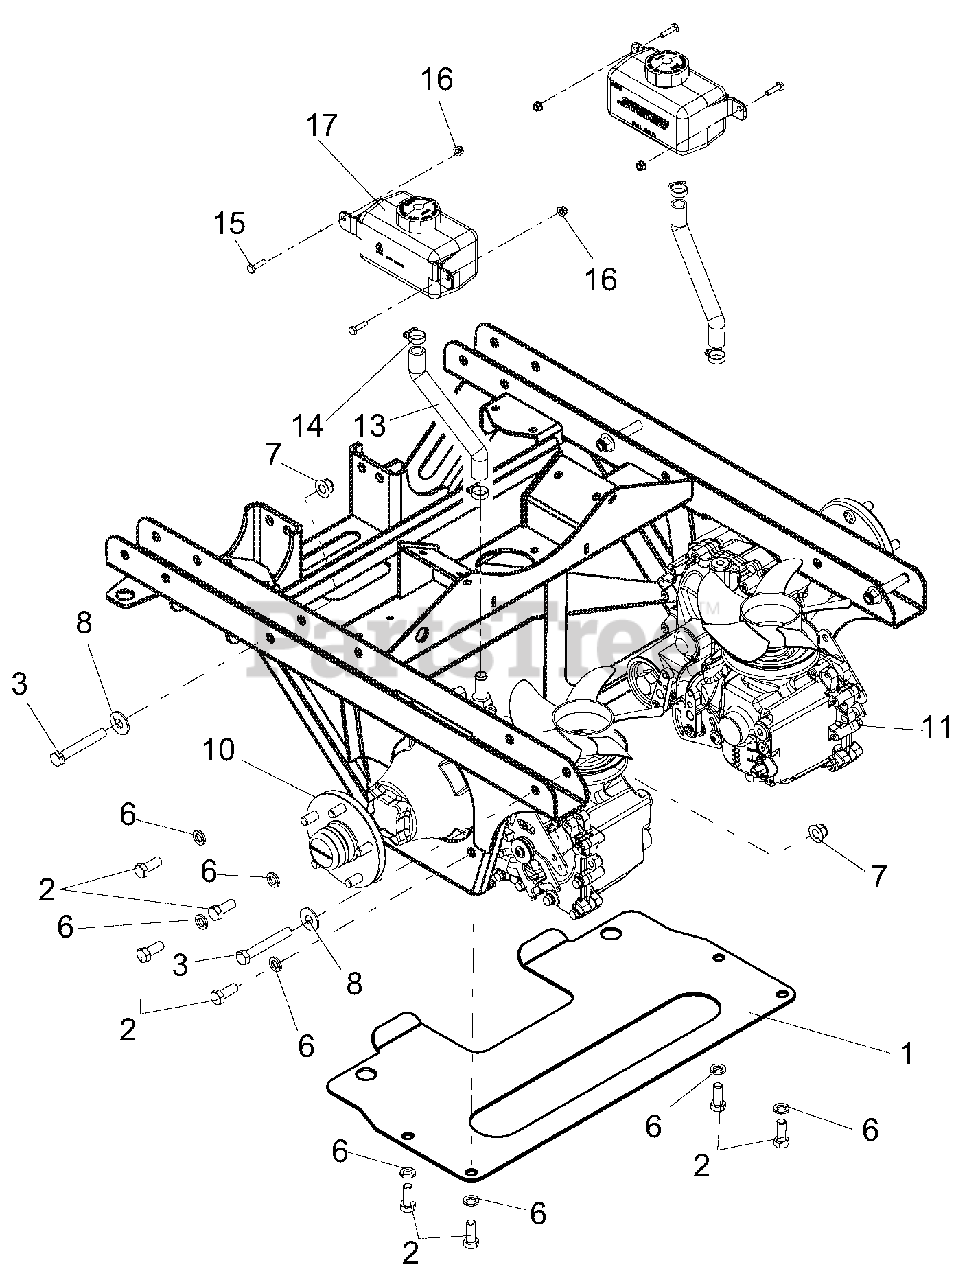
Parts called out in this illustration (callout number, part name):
1	PLATE, TRANSMISSION CONNECTING
2	BLT-HEX .50-13X1.25 GR5 YWZC
3	BLT-HEX .50-13X3.50 GR5 YWZC
6	WSHR-LK .50X.125 REG YWZC
7	NUT-LK-NYL-FLG .50-13 YWZC
8	WSHR-FL-STL.563X1.38X.109YWZC
10	TRANS, R.H. HG ZT-5400
11	TRANS, LH HG ZT-5400
13	HOSE, HYDRO OVERFLOW
14	CLAMP, .88 DIA HOSE
15	BLT-HEX .25-20X1.00 GR5 YWZC
16	NUT-LK-NYL-FLG .25-20 YWZC
17	TANK, HYD 1000ML
